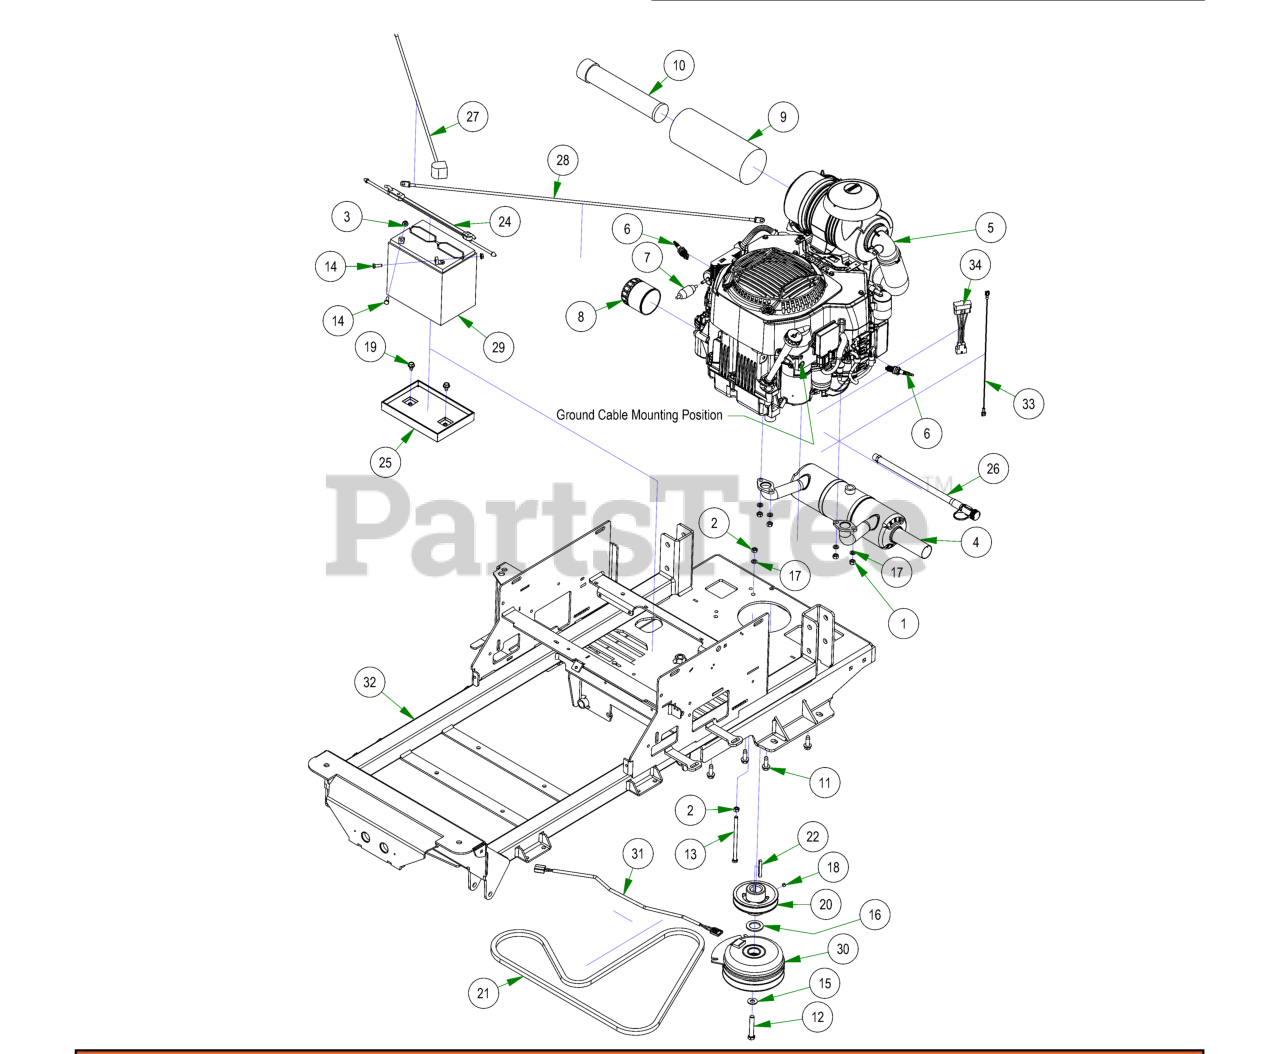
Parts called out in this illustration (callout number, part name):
1	M8-1.25 DIN 934 HEX NUT (CL.8) ZINC
2	5/16-18 HEX NUT ZINC
3	1/4-20 HEX SERRATED FLANGE NUT HARD/ZINC
4	2023 ECV749 Maverick HD Muffler
5	Kohler Command 26.5hp EFI CV749
6	Spark Plug
7	25/26 HP Kohler Fuel Filter
8	Oil Filter
9	Canister Air Filter- Outer
10	Canister Air Filter- Inner
11	3/8-16 X 1-1/8 HEX WASHER UNSLOT SERRATED (TRI-LOB) TRS ZINC YELLOW
12	7/16-20 X 2-1/2 HEX Bolt GR 8 W/ Patch
13	5/16-18 X 5-1/2 HEX CAP SCREW (GR.5) ZINC
14	1/4-20 X 3/4 HEX CAP SCREW (GR.5) ZINC
15	3/8 FLAT WASHER USS (1" OD) ZINC
16	1.140 ID X 1.750 OD X .132 THICK FLAT WASHER PLAIN
17	5/16 SPLIT LOCKWASHER ZINC
18	5/16-24 X 1/4 SOCKET SET SCREW (CUP PT) PLAIN
19	5/16-18 X 1/2 HWH unslot (F) tcs zinc
20	4 3/4 Motor Pulley
21	75.8" Pump Belt
22	1/4 X 2 SQ MACHINERY KEY 1018 STL PLAIN
23	2023 Battery Hold Down Assembly
24	2023 Rubber Battery Hold Down Strap
25	Battery Tray
26	Kohler Oil Drain
27	24 inch Black Cable – MZ/ZT
28	36" Red Battery Cable
29	SP-35 Battery
30	Clutch Assembly
31	Clutch Pigtail
32	2023 Maverick Frame - Painted
33	Compact Outlaw/Honda Starter Jumper Wire
34	2019 Harness Adaptor-Carbureted Yamaha
